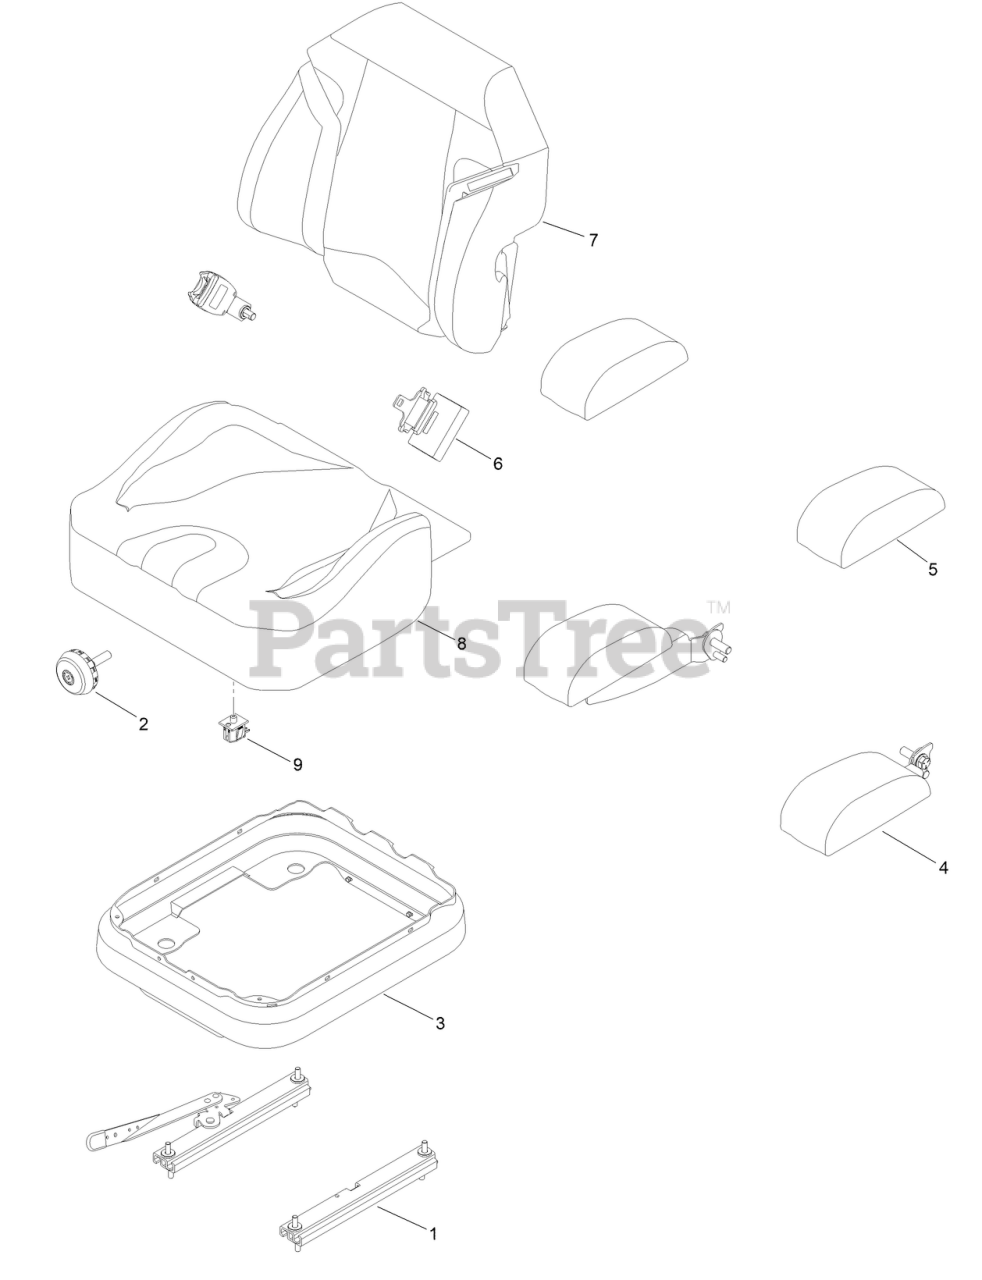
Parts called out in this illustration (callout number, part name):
1	SET, SEAT TRACK
2	KNOB-WEIGHT ADJUST ASM
3	BELLOWS-SEAT
4	ARM REST KIT
5	PADS-ARMREST W/ HARDWARE
6	KIT-SEAT BELT
7	COVER-BACK, SEAT
8	COVER-BOTTOM, SEAT
9	SWITCH-PLUNGER, ON-(ON)
